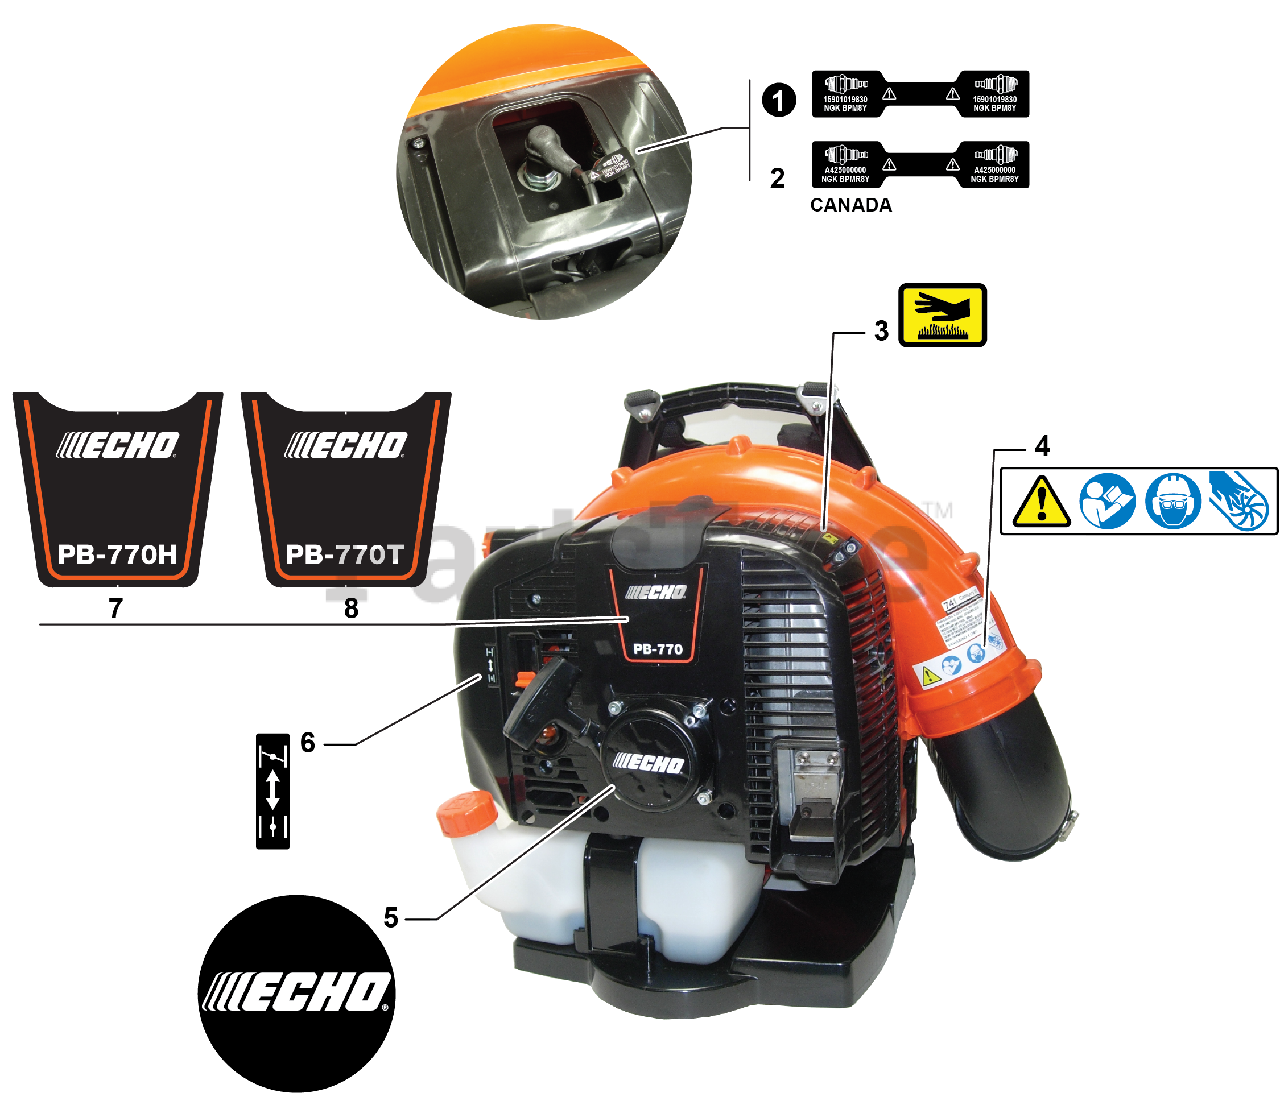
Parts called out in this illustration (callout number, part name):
1	LABEL, SPARK PLUG - BPM8Y
2	LABEL, SPARK PLUG - BPMR8Y
3	LABEL, CAUTION - HOT
4	LABEL, CAUTION - ISO
5	LABEL, ECHO
6	LABEL, CHOKE
7	LABEL, PB-770H
8	LABEL, PB-770T
